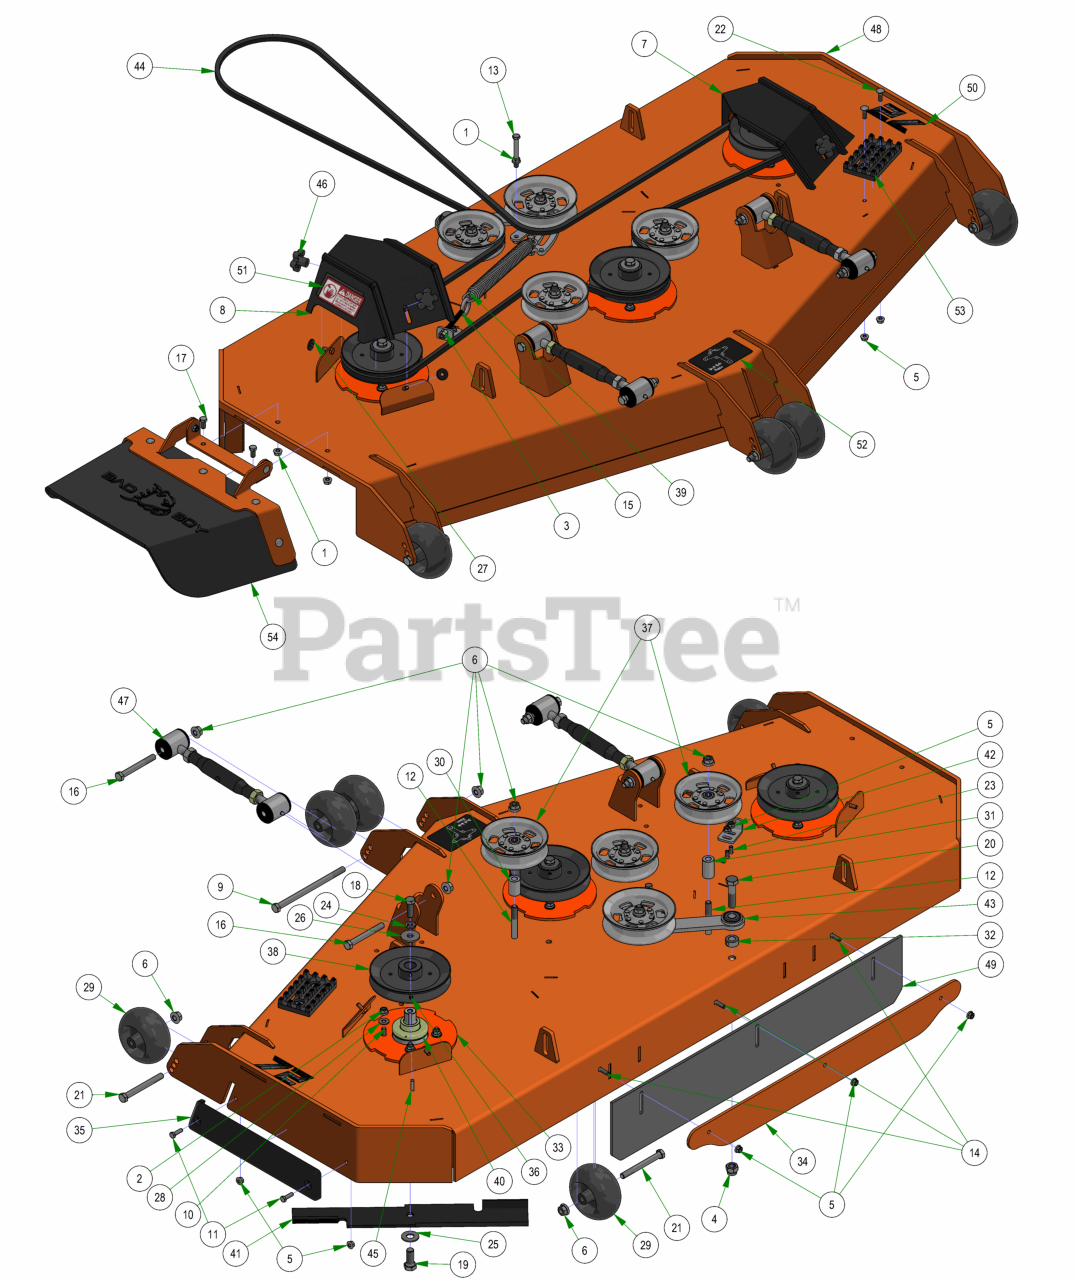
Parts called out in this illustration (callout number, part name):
1	3/8-16 HEX SERRATED FLANGE NUT HARD/ZINC
2	3/8-16 NYLON INSERT FLANGE LOCKNUT (GR.F) ZINC
3	3/8-16 HEX NUT ZINC
4	5/8-11 NYLON INSERT LOCKNUT ZINC
5	5/16-18 NYLON INSERT FLANGE LOCKNUT ZINC
6	1/2-13 NYLON INSERT FLANGE LOCKNUT ZINC
7	2019 72" Left Outlaw Gen2 Pulley Cover
8	2019 72" Right Outlaw Gen2 Pulley Cover
9	1/2-13 X 8 HEX CAP SCREW GR 5 ZINC
10	3/8-16 X 1-3/4 HEX C/S (GR.5) ZC
11	5/16-18 X 1 HEX CAP SCREW (GR.5) ZINC
12	1/2-13 X 3-1/2 HEX FLANGE BOLT (GR.8) ZINC
13	3/8-16 X 3 HEX CAP SCREW (GR.5) ZINC
14	5/16-18 X 1-1/4 CARRIAGE BOLT ZINC
15	4" 3/8-16 Eye Bolt
16	1/2-13 X 4 HEX CAP SCREW (GR.8) ZINC YELLOW
17	3/8-16 X 3/4 HEX CAP SCREW (GR.5) ZINC
18	1/2-20 X 1-1/2 HEX CAP SCREW (GR.5) ZINC
19	5/8-18 X 1-1/2 HEX CAP SCREW (GR.8) ZINC YELLOW
20	5/8-11 X 2-1/2 HEX CAP SCREW (GR.5) ZINC
21	1/2-13 X 4-1/2 HEX CAP SCREW (GR.5) ZINC
22	5/16-18 X 1 CARRIAGE BOLT (GR.8) ZINC
23	5/16-18 X 7/8 CARRIAGE BOLT ZINC
24	1/2 SPLIT LOCKWASHER (GR.8) ZINC/YELLOW
25	5/8 USS FLAT WASHER (1-3/4" OD) GR.8 ZINC YELLOW
26	1/2 BELLEVILLE WASHER (1-5/8 OD X .140 THK) ZINC
27	.360 ID X .983 OD X .120 THICK FLAT WASHER NYLON BLACK
28	5/16 USS FLAT WASHER (7/8 OD) ZINC
29	2019 Deck Wheel
30	.502 ID X .750 OD X 1.500 Long Spacer
31	1 3/4" Pulley Spacer
32	5/8 SOLID SHAFT COLLAR (W/1 SET SCREW) ZINC
33	Deck Spindle Support Plate
34	61 Bolt in Baffle Deck v2 Stripping Plate
35	REVISED TRIM BUMPER_20180226
36	5/16-24 X 1/4 SOCKET SET SCREW (CUP PT) PLAIN
37	5-3/4 Idler Pulley
38	7" Deck Pulley
39	2019 Outlaw Gen2 Deck Spring
40	OUTLAW SPINDLE ASSEMBLY
41	72" High Lift Fusion Blade
42	2019 Deck Eye Bolt Tab
43	2019 Rebel Rogue Deck Idler
44	B202 Belt for 72" Outlaw
45	1/4 X 1 SQ MACHINERY KEY 1018 STL PLN
46	5/16" Knob
47	Turnbuckle Assembly (M20-2.5)
48	2019 Sloped 72" Deck
49	R Series Rubber For Deck
50	72" Deck Decal
51	Danger Decal-Spindle/Discharge
52	2019 Rebel & Rogue Deck Belt Route Decal
53	Deck Step Assembly
54	2019 Outlaw Gen2 Chute Assembly
